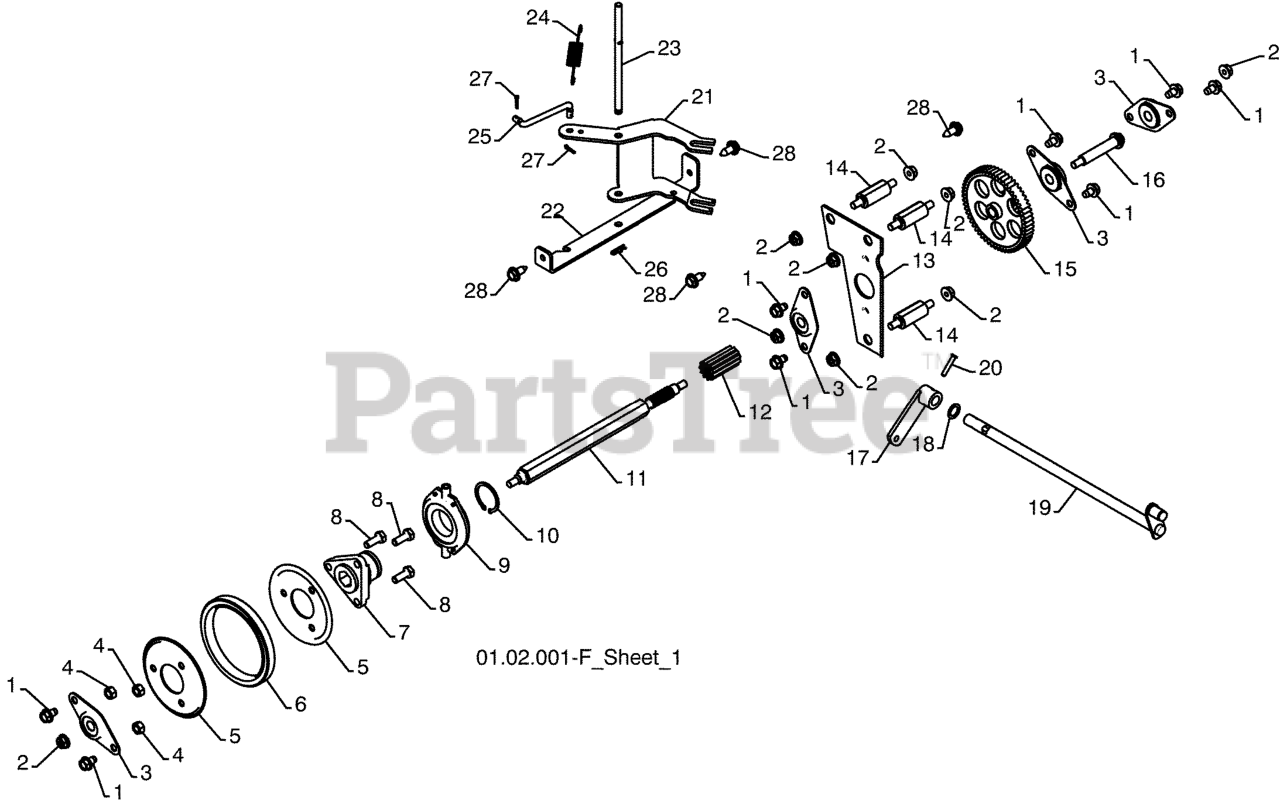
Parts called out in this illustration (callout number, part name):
1	HEAD ASSY SPEED
2	SCREW #10-24 X 5/8
3	DRIVE PLATE WELDMENT
4	SHAFT.HEX.SHORT
5	TRUNNION BEARING ASSY
6	RETAINING RING (2 2)(3 2)
7	BOLT
8	BEARING FLANGE
9	SPACER, BEARING
10	LEVER.SHIFTER.PLATE.BLACK
11	BRACKET, SHIFTER SUPPORT
12	PIN, PIVOT LEVER
13	RETAINER CLIP PM
14	SCREW
15	BOLT 5/16-18 X .500
16	PLATE.DRIVE.MOUNTING.BLACK
17	NUT.FLANGE.5/16
18	PULLEY.TRACTION.7.75
19	WASHER, FLAT
20	WASHER.LOCK.HVY.HLCL.SPR.5/16
21	SCREW 5/16-18 X .750
22	ARM.IDLER.BRAKE.BLACK
23	PULLEY.W/SPACER.2.75
24	BRACKET, IDLER PIVOT
25	PIN, IDLER PIVOT
26	HEX BOLT
27	LOCKNUT 5/16-18
28	RP SPRING, TRACTION IDLER
29	ARM, IDLER
30	PULLEY.W/SPACER.2.25
31	BOLT.5/16-18X1-1/4 FULL.THREAD
32	STEEL WASHER
33	NUT.CENTERLOCK.5/16-
34	SCREW, HEX HD 3/8-24 X 1-3/8
35	LOCKWASHER
36	WASHER, FLAT 3/8
37	PULLEY,ENGINE TRACTION DRIVE
38	SPACER.ENGINE.PULLEY
39	SPRING.RETURN
40	BELT.GUIDE.RH
42	RP BUSHING, IDLER PIVOT
43	WASHER EXT TOOTH LOCK 5/16
44	SPRING, BRAKE
45	SCREW
